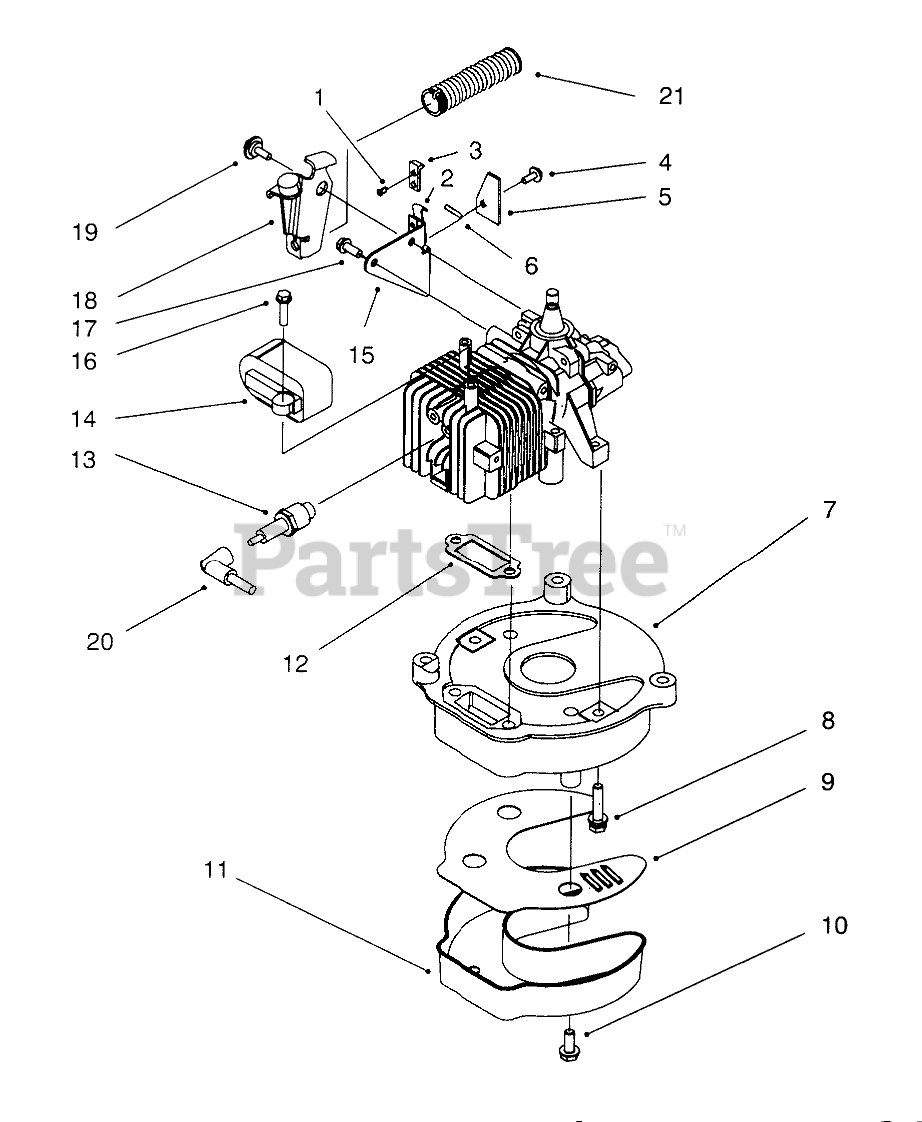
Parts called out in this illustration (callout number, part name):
1	RIVET-PLASTIC
2	STRAP-GROUND
3	STRAP-INSULATION
4	SCREW
5	STOP-GROUND STRAP
6	ELECTRICAL LEAD ASM
7	PLATE-MUFFLER V
8	SCREW V
9	Baffle
10	SCREW
11	Cover-Muffler
12	GASKET-EXH. VF
13	SPARK PLUG
14	Ignition Assembly (Incl. Ref. #20)
15	PLATE-BRAKE
16	SCREW
17	SCREW
18	PLATE-BRAKE
19	SCREW-SHOULDER
20	HT LEAD&COVER XEV
21	SPRING-COMPRESSION
